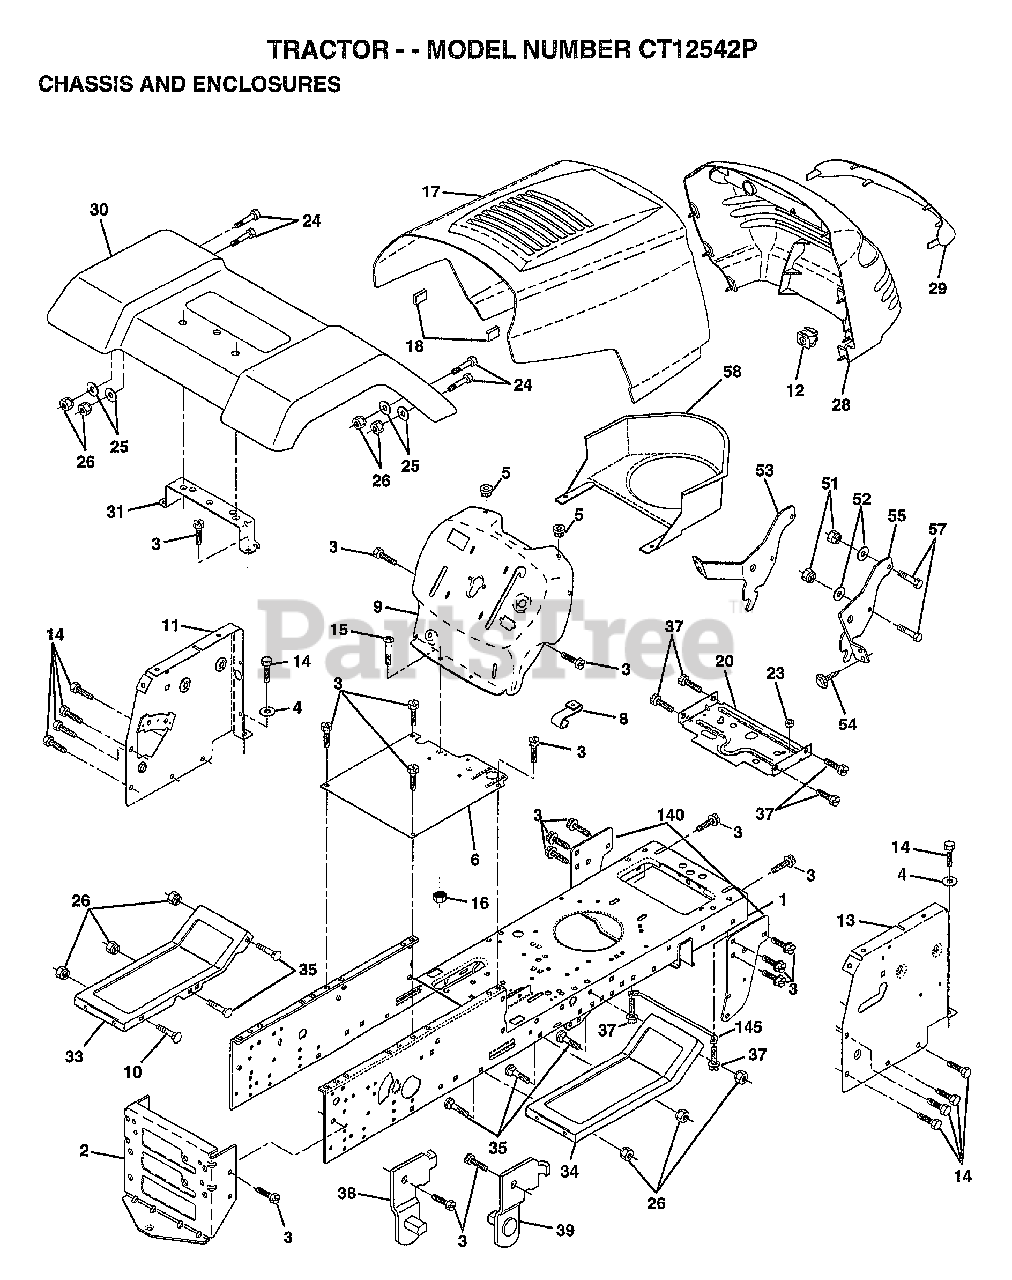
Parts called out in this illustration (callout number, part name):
3	SCREW
4	WASHER
5	BUMPER-HOOD/DASH
6	SADDLE-SILKSCREEN
8	CLIP.RETAINER
9	DASH SILKSCREEN
11	"PANEL-DASH,LH"
12	CLIP.TINNERMAN
14	SCREW LT
15	SCREW
17	HOOD.STEEL.ASSY
20	"PLATE-MTG,BATT/FU"
24	BOLT
25	WASHER
26	NUT
28	GRILLE-MS428
29	LENS GRILLE
30	FENDER PNT LT
31	BRKT FENDER
33	FOOTREST.LH.PERF.
34	FOOTREST.RH.PERF.
35	BOLT
37	SCREW LT
38	BRACKET ASM LH
39	BRACKET ASM RH
51	NUT
52	WASHER
53	BRACKET.GRILLE.LH
54	SCREW.HEX.WS.HD
55	BRACKET.GRILLE.RH
58	AIR DUCT
140	BRKT SUSPENSION
145	"ROD POVOT,CHASSIS"
